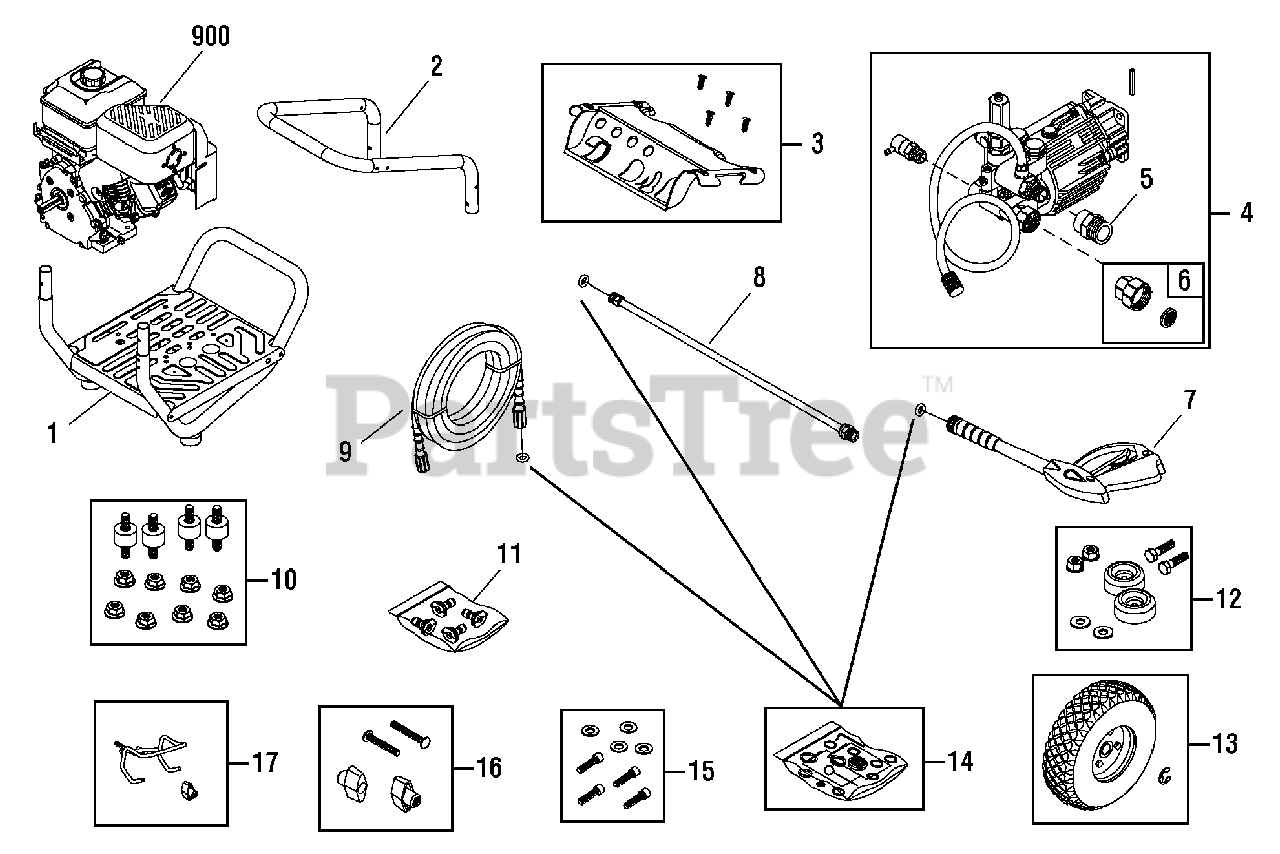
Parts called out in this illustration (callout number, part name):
6	CONNECTOR, Garden Hose
7	GUN
8	EXTENSION, QC
10	KIT, Vibration Mount
11	KIT, QC Nozzles
12	MOUNT, Vibration
14	KIT, O-Ring
15	KIT, Hardware, Pump Mounting
16	KIT, Hardware, Handle
900	* ENGINE
